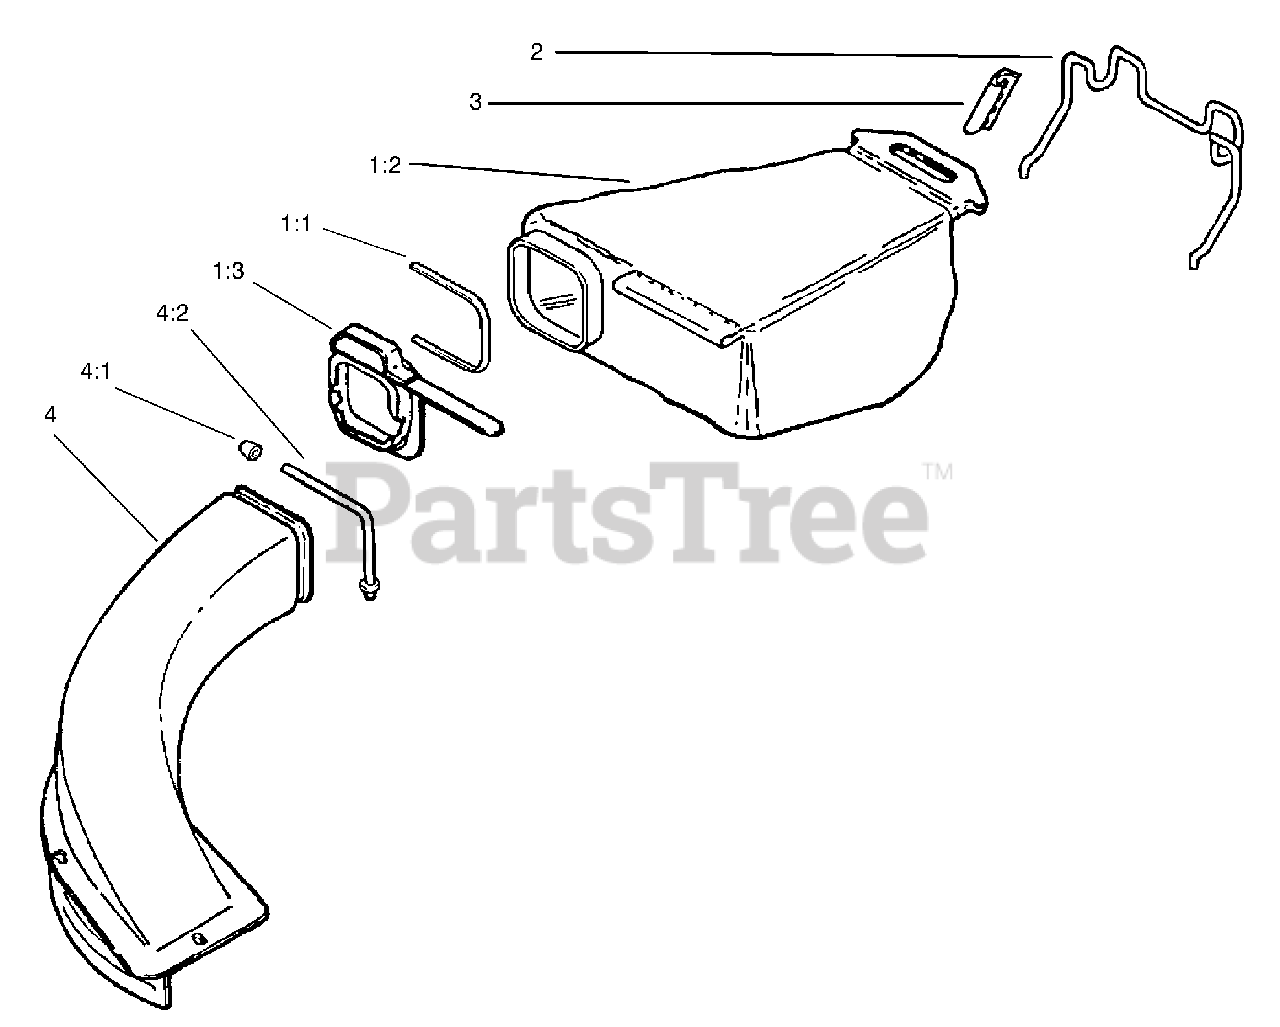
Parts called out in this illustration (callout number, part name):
1:1	Strap-Tie
1:2	Replacement Bag ASM.
2	Hanger-Wire
3	Clamp-Hanger
4	Chute & Support ASM
4:1	Nut-Cap
4:2	Support-Chute
